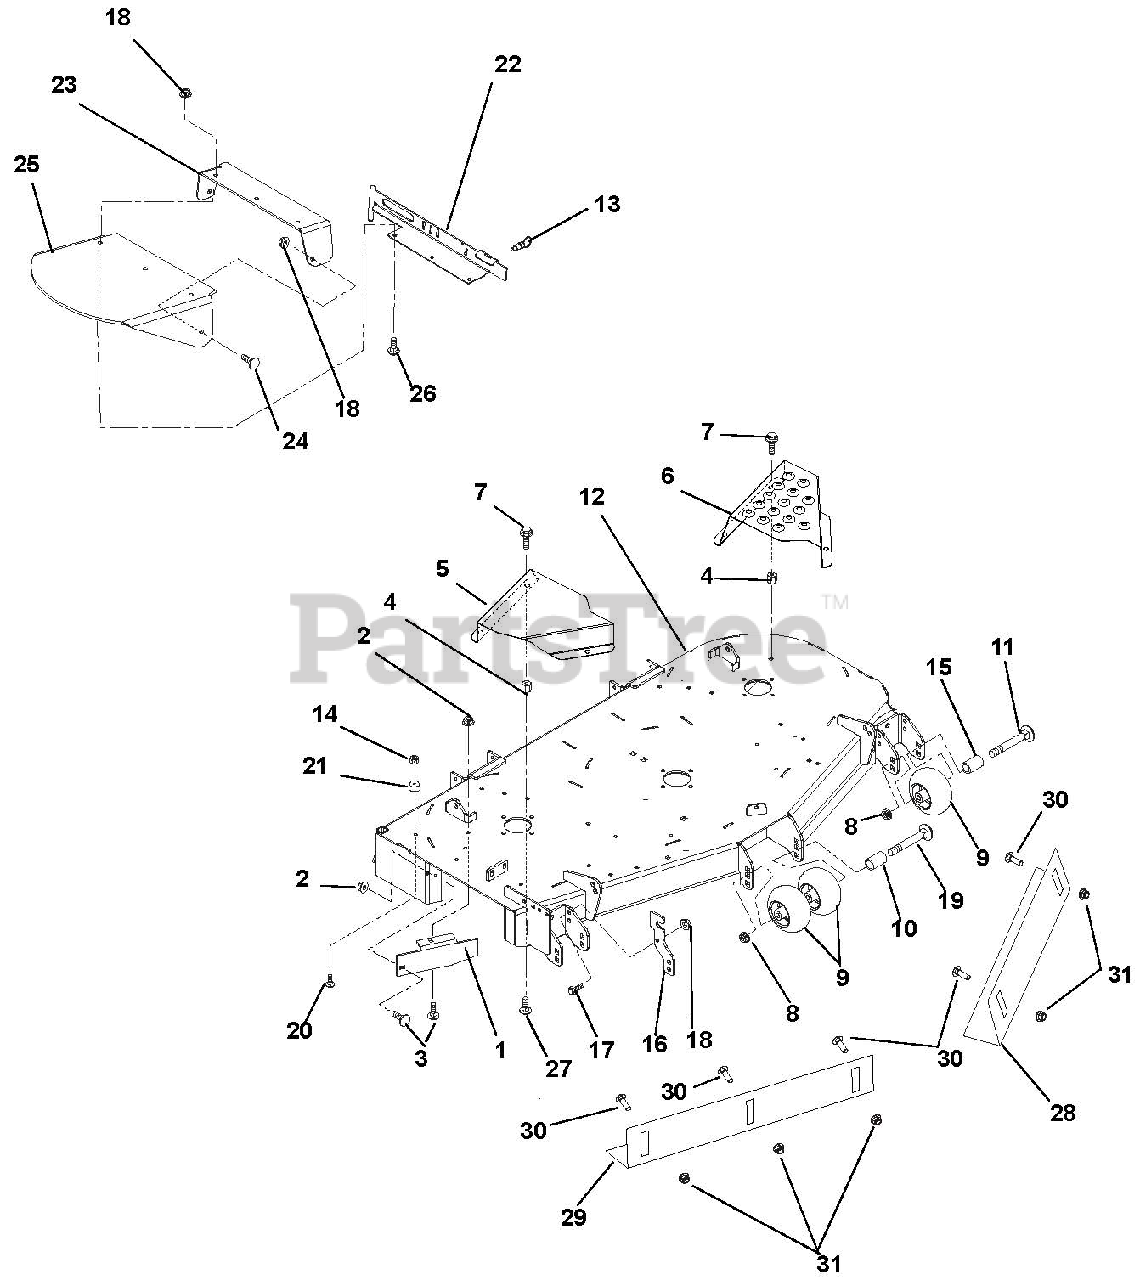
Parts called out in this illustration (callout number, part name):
1	60-in. Discharge Baffle
2	Nut, Nyloc Flange .31-18
3	Bolt, Round Head Square Neck .31-18 x 1.00 Grade 5
4	Nut, Heavy Hex .38-16
5	60" Spindle Guard Right Hand
6	60" Spindle Guard Left Hand
7	Nut, Spin Lock Flange .375-16
8	Nut .50-13 Nyloc Flange
9	Anti-Scalp Wheel
11	Bolt, Round Head Square Neck .50-13 x 5.00
12	60" Pro-Master 200 Side Discharge Deck Weldment
13	Pin, Plunger Pull .50-13 Thread x .310 Diameter
14	Nut, Locking Center .31-18
15	Spacer, .510 x .625 x 3.35
16	Chute, Storage Bracket
17	Bolt, Hex .38-16 x 1.00 Grade 5
18	Nut, .38-16 Nyloc Flange
19	Bolt, Round Head Square Neck .50-13 x 8.50
20	Bolt, Round Head Square Neck .31-18 x 1.50
21	Bumper, Recessed 1.50 x .63 , .31 Thru Hole
22	Weldment, 52"-60" Discharge Chute Mounting
23	Discharge Chute Support with Decal
24	Bolt, Round Head Square Neck .38-16 x 1.00 Grade 5
25	Chute, Rubber Discharge
26	Bolt, Round Head Square Neck .38-16 x 1.25 Grade 5
27	Bolt, Hex .38-16 x 1.25 Grade 5
28	Baffle, 60" Vacuum Left Hand
29	Baffle, 60" Vacuum Right Hand
30	Bolt, Round Head Square Neck .31-18 x .75 Grade 5
31	Nut, Lock Nyloc .31-18
